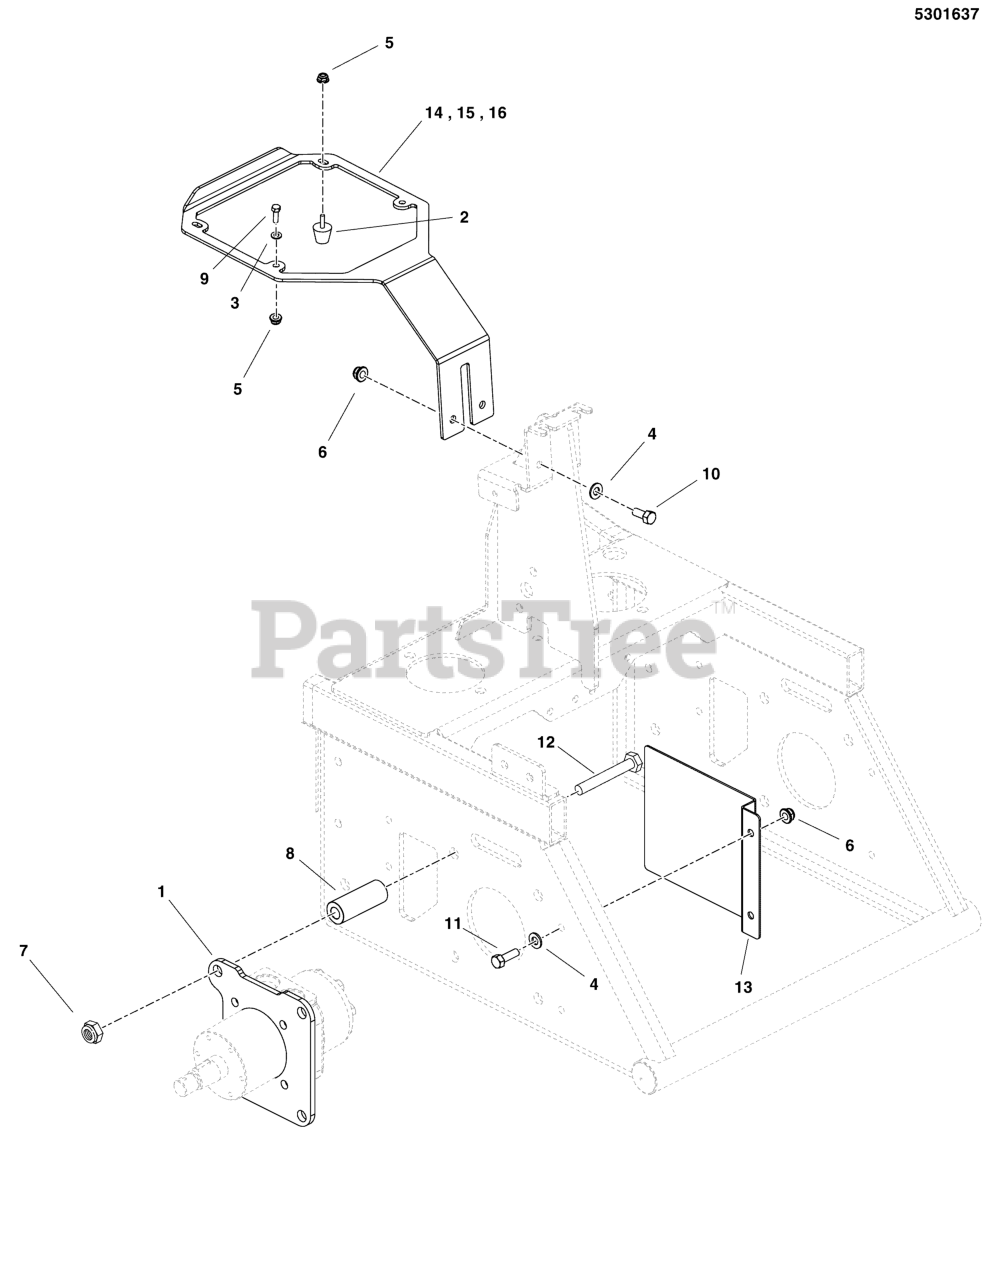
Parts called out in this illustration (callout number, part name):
1	PLATE, SPACER
2	BUMPER, RUBBER 1/4-20
3	WASHER, 1/4 SAE
4	WASHER, 5/16" SAE
5	NUT, 1/4-20 HEX NYLOCK FLANGE
6	NUT, 5/16-18 HEX NYLOCK FLANGE
7	NUT, Hex Flange, Nylock, 1/2-13
8	SPACER, .50 X 1.00 X 2.00
9	BOLT, 1/4-20 X 3/4 GD5 YZ
10	BOLT, 5/16-18 X 3/4 GD5
11	BOLT, 5/16-18 X 1 GD5 YZ
12	BOLT, 1/2-13 X 3-1/2, HEX HD, GD5, CZ (SV)
13	PLATE, HEAT SHIELD, WHEEL MOTOR, 48-RED
14	PLATE, COOLER MOUNT BRACKET
15	PLATE, COOLER MOUNT BRACKET
16	PLATE, COOLER MOUNT BRACKET
